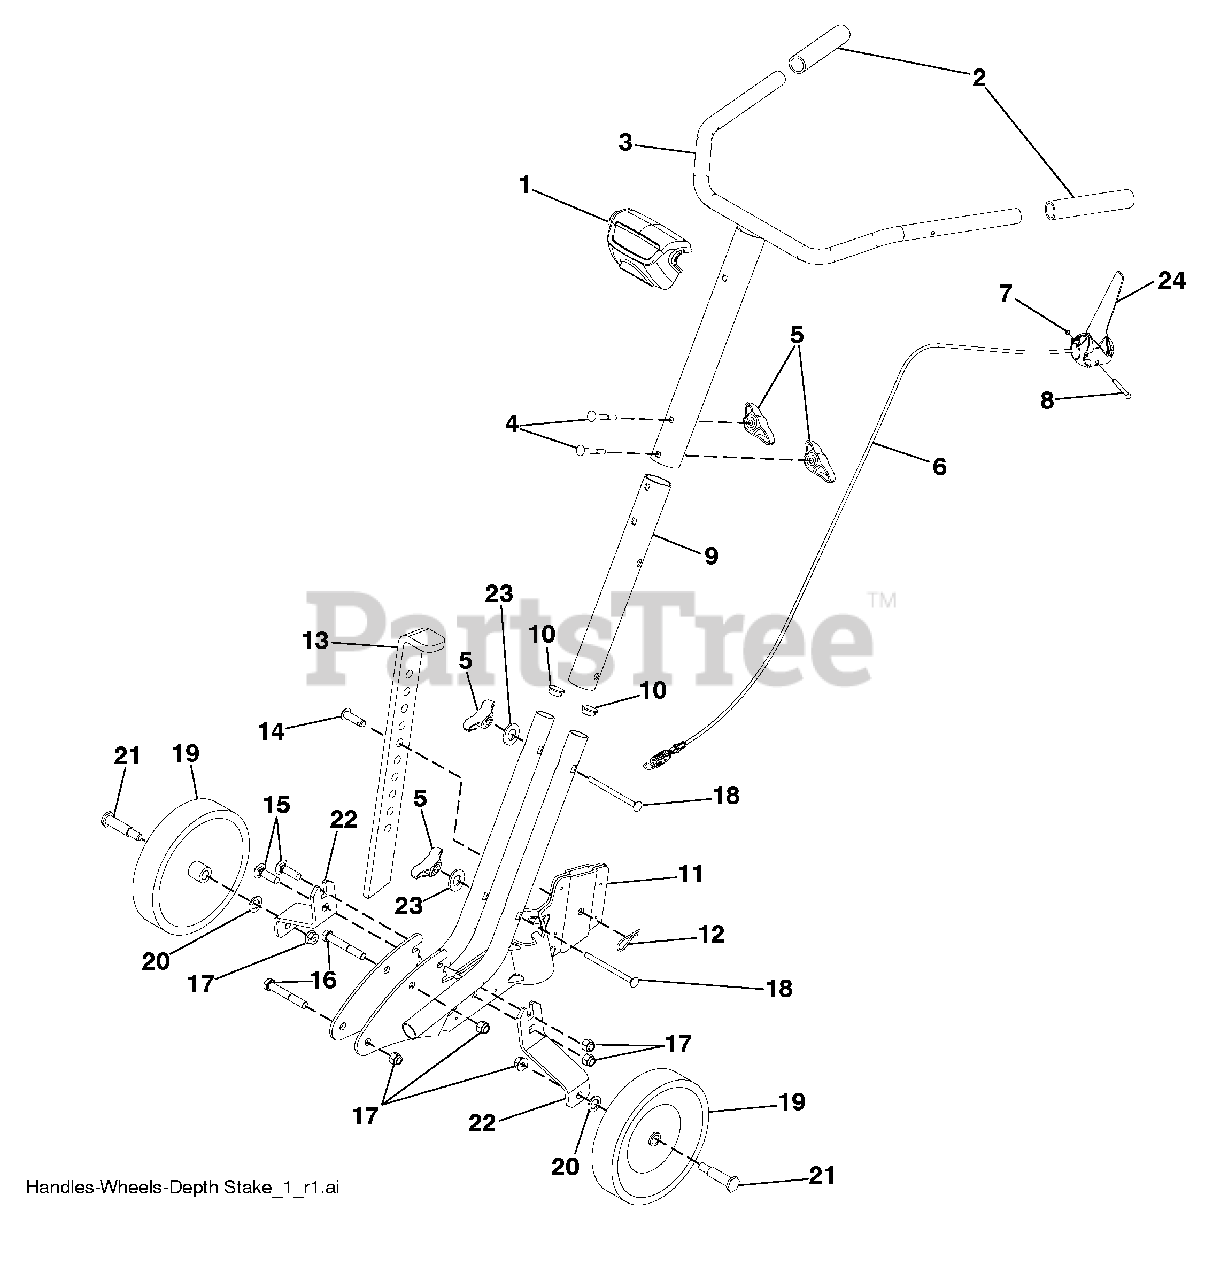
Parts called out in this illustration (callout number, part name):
1	Console Tiller Handle
2	Grip Handle
3	Assembly Handle Column
4	Bolt 5/16 - 18 x 2.50
5	Knob Wing
6	Lever Control Tine
7	Retainer Ring
8	Pin Pivot
9	Handle Lower
10	Plug Snap In
11	Weldment Transport Arm
12	Clip Hairpin
13	Stake Depth
14	Pin Clevis
15	Bolt 3/8 - 16 x 1-1/4
16	Screw Hex Head 3/8 - 16 x 2.5
17	Nut Lock Flg 3/8 - 16 unc
18	Bolt 5/16 - 18 x 4.5
19	Wheel
20	Washer 17/32 x 7/8 x 16 Ga.
21	Bolt Shoulder "A" 2.28 " B" 1.53
22	Bracket Wheel
23	Washer 11/32 x 3/4 x 16 Ga.
24	Lever Control
